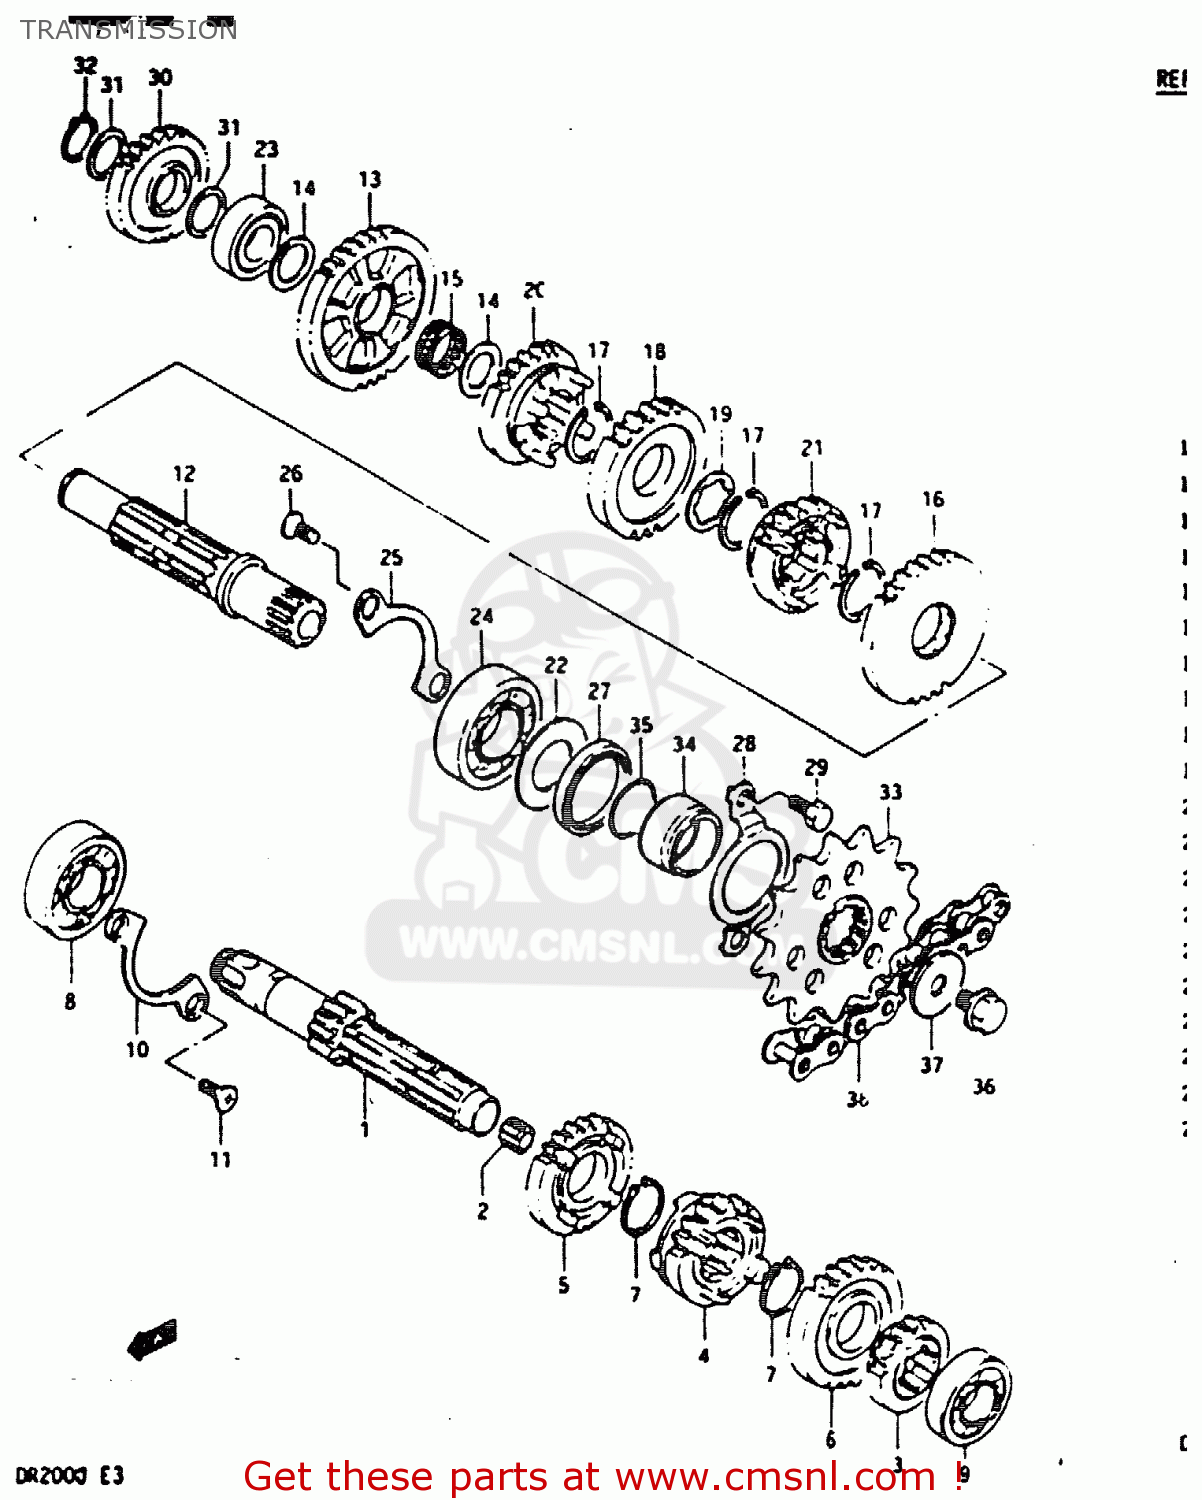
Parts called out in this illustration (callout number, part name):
1	SHAFT,COUNTER (NT:11)
2	BUSH
3	GEAR,2ND DRIVE
4	GEAR,THIRD DRIVE (NT:16)
5	GEAR,4TH DRIVE
6	GEAR,FIFTH DRIVE
7	CIRCLIP
8	BEARING
9	BEARING, LH
10	RETAINER,DRIVE SHAFT BEARING
11	SCREW
12	SHAFT COMP,DRIVE
13	GEAR,1ST DRIVEN
14	WASHER,THRUST
15	BEARING(17X21X9.8)
16	GEAR,SECOND DRIVEN (NT:29)
17	CIRCLIP
18	GEAR,THIRD DRIVEN (NT:23)
19	WASHER,LOCK
20	GEAR,FOURTH DRIVEN (NT:23)
21	GEAR,5TH DRIVEN
22	WASHER,OIL SEALING
23	BEARING(17X36X12)
24	BEARING(22X50X14)
25	RETAINER,DRIVE SHAFT BEARING
26	SCREW
27	SEAL,OIL(30X40X6)
28	RETAINER,DRIVESHAFT O
29	BOLT
30	GEAR,KICK STARTER IDLE
31	WASHER
32	CIRCLIP
33	SPROCKET,ENGINE
34	SPACER,ENGINE SPROCKET
35	O RING(D:2.5,ID:21)
36	BOLT
37	WASHER
38	CHAIN ASSEMBLY,DRIVE
